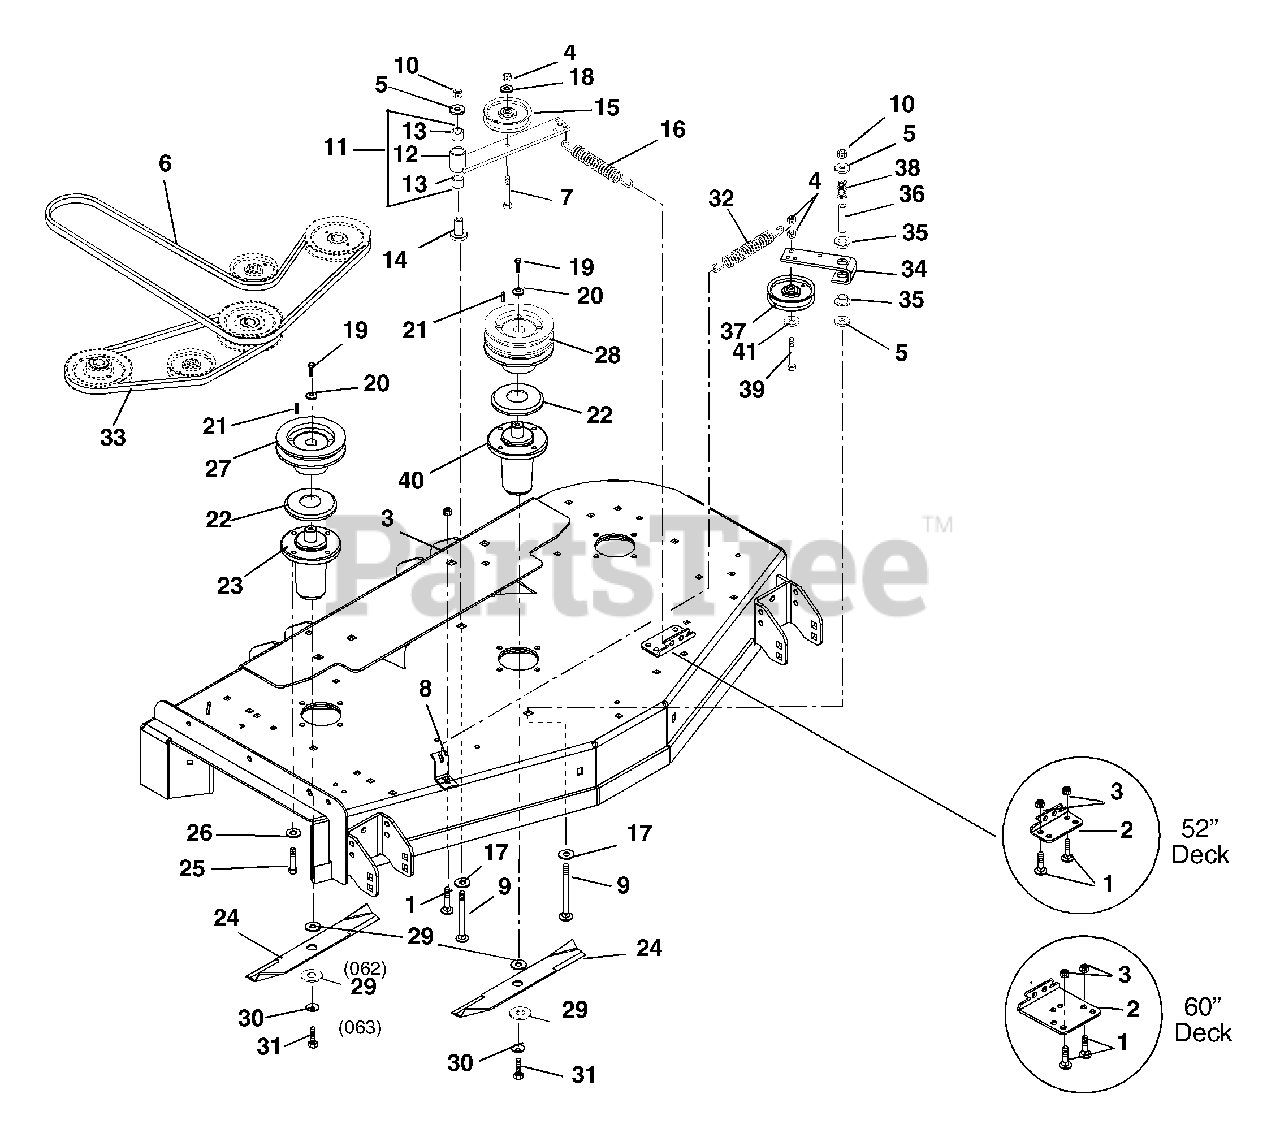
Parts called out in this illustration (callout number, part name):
1	@BLT-RDHDSQNK .38-16X.75 G5YZ
1	@BLT-RDHDSQNK .38-16X1.25 G2YZ
2	BRACKET, SPRING - ORANGE
2	BRACKET, SPRING
3	@NUT-LK-TOP-FLG .38-16 YWZC
4	@NUT-LK-CTR .38-16 YWZC
5	WSHR-FL-STL .531X1.250X.10 YWZ
6	V-BELT, HB-WRAPPED
6	V-BELT, B-WRAPPED
7	@BLT-HEX .38-16X2.75 GR5 YWZC
8	ANCHOR, SPRING - ORANGE
9	@BLT-RDHDSQNK .50-13X3.50 G5YZ
10	@NUT-LK-TOP-FLG .50-13 YWZC
11	ASSEMBLY, IDLER PIVOT ARM
12	WELDMENT, IDLER PIVOT ARM
13	BRG, 1.00 X 1.12 X .75
14	BEARING, PEDESTAL
15	IDLER-FLAT 4.00X.38 (2.00 W)
16	SG-EXT-.090X1.00X6.00
17	WSHR-FL-STL.755X1.375X.062YWZC
18	WSHR-FL-STL .375X1.125X.065YWZ
19	BLT-HEX .38-16X1.00 YZ GR8
20	WASHER, CUPPED SERRATED, .375
21	KEY, SQ .25X.25X1.00 RC 40-50
22	SLINGER, DUST
23	ASM,MAINT FREE SPINDLE
24	BLADE, MOWER (18.00")
24	BLADE - MULCHING (18.00")
24	BLADE, MOWER (20.50")
24	BLADE, TUNG MULCH MOWER 60"
25	@BLT-HEX .38-16X1.00 GR5 YWZC
26	@WSHR-LK .38X.094 REG YWZC
27	WELDMENT, SPINDLE SHEAVE 5.00
27	WELDMENT, SPINDLE SHEAVE 6.00
28	SHEAVE, DOUBLE (5.25")
28	SHEAVE, DOUBLE (6.25")
29	WSHR-FLT .640X1.75X.250 YWZC
30	WSHR-BLVL .669X1.535X.138
31	BLT-HEX .62-18X1.75 GR8 YWZC
32	SPRING, EXT
33	V-BELT, HB-COGGED
33	V-BELT, HB-RAW EDGE
34	ARM,IDLER PIVOT
35	BSHG-FLG .762X1.0X.580X1.48 NY
36	SPACER .560X.750X2.437 ST
37	V-IDLER, 4.00X.38
38	SG-COMP .085X.80X1.00 WLD36
39	@BLT-HEX .38-16X2.25 GR5 YWZC
40	ASM,MAINT FREE SPINDLE
41	@WSHR-FL-STL.406X.812X.065 YWZ
